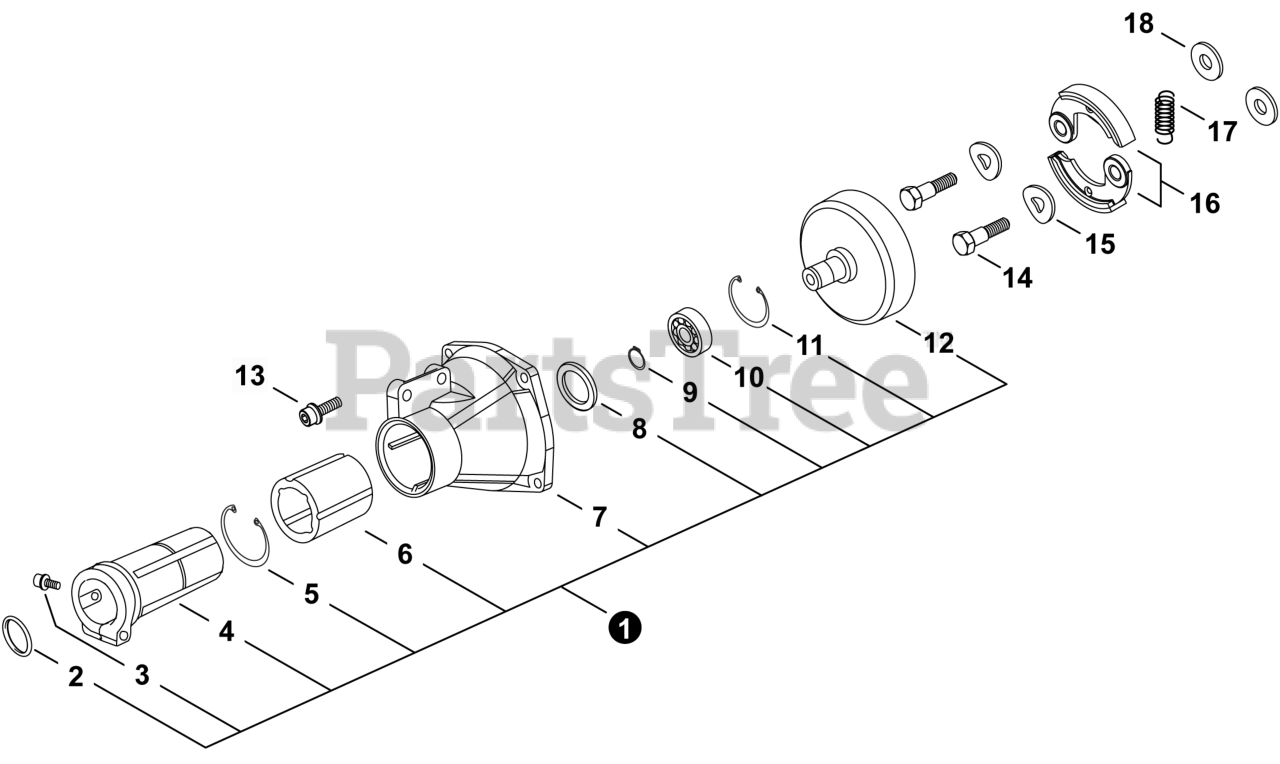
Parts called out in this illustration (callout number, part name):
1	CASE ASSY, CLUTCH
3	BOLT M5
5	RING, SNAP
6	CUSHION
7	CASE, CLUTCH
9	RING, SNAP
10	BEARING, BALL
11	RING, SNAP
12	DRUM, CLUTCH
14	BOLT, CLUTCH
15	WASHER 10.2×18×1.0
16	SHOE SET, CLUTCH
17	SPRING, CLUTCH
18	WASHER 8.2×17×1.6
